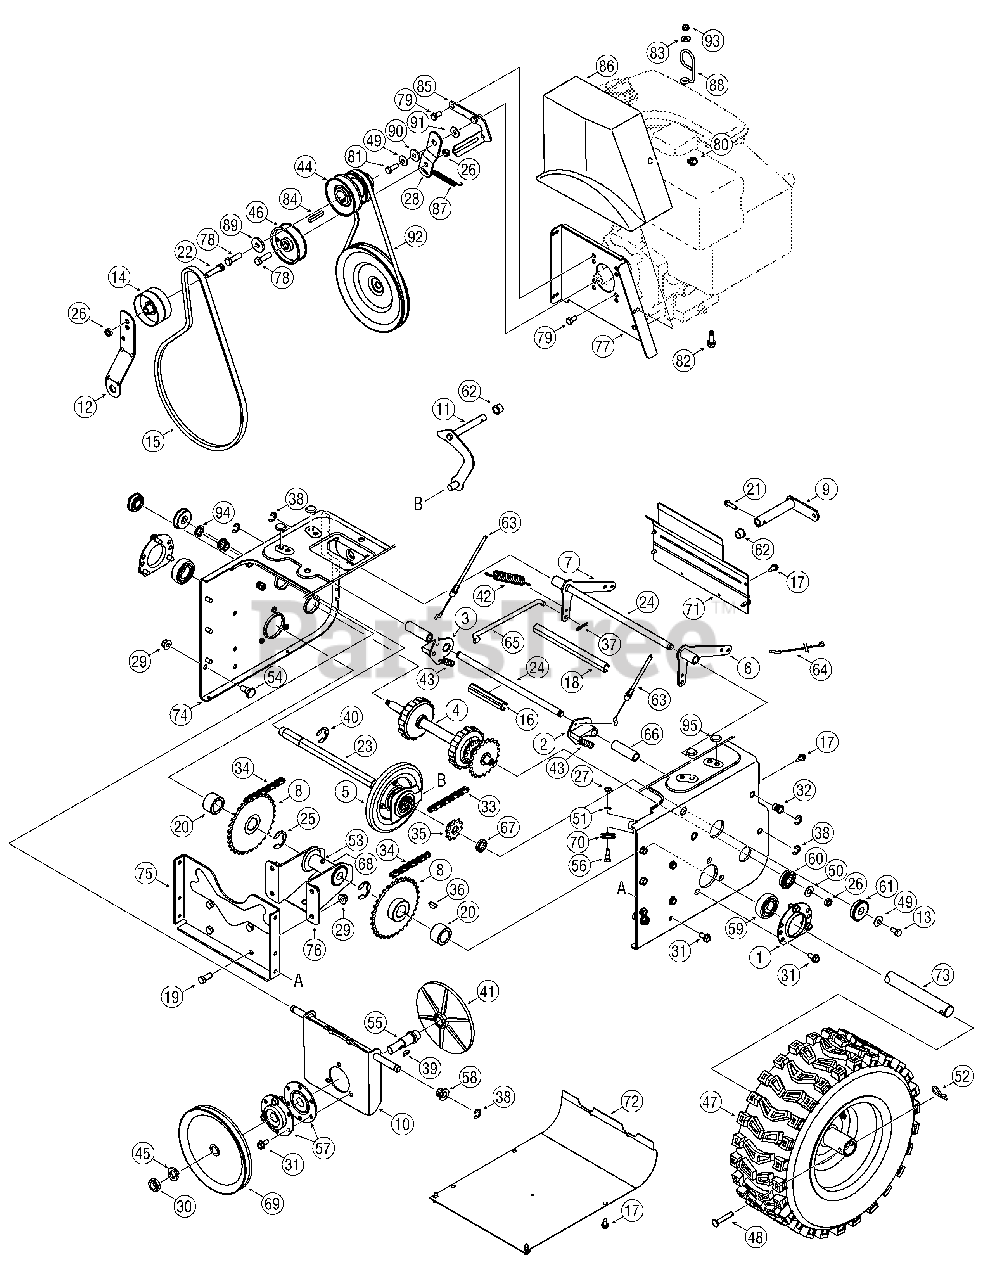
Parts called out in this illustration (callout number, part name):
1	Housing, Bearing
2	Dogg, Steering Drive, LH
3	Dogg, Steering Drive, RH
4	Shaft Assembly, Steering
5	Assembly, Friction Wheel
11	Rod Assembly, Shift
12	Brkt., Idler, Auger
13	Screw, Hex Cap Lock,
14	Idler, Flat, 2.75 OD
15	V-Belt, 1/2 x 44.0
16	Spcr., .51 ID x 3.66 Lg.
17	Screw, Hex Wash.
18	Spcr., .51 ID x 7.895 Lg.
19	Screw, Hex Cap, 3/8-16
20	Spcr., 1.0 ID x 1.50 OD
21	Screw, Hex, 1/4-20 x 1.00
22	Screw, 3/8-24 x 1.50
23	Shaft, Hex Drive
24	Shaft, Actuator
25	Ring, Retainer
26	Nut, Hex Insert Jam Lock
27	Nut, Hex, 1/4-28 GR5
28	Bracket, Idler, Drive
29	Nut, Hx Flnge Insert Lk
30	Nut, Hx Insert Jam Lk
31	TT Screw, 5/16-18 x .750
32	Nut, Insert 3/8-16
33	Chain, Endless, #41 x 36L
34	Chain, #420 x 40L
35	Sprocket, #41 x 10T
36	Key, Woodruff
37	Pin, Internal Cotter
38	E-Ring
39	Key, Hi-Pro, 3/16 x 5/8
40	Ring, Retaining
41	Plate, Drive
42	Spring, Extension
43	Spring, Extension
44	Pulley, Dbl, 3.25 OD
45	Washer, Lock, 5/8
46	Pulley, Flat Idler, 3.0 OD
48	Pin, Clevis
49	Wsh, Bell., .34 x .872 x .06
50	Wash, .406 x .875 x .059
51	Washer, Lock, 1/4
52	Pin, Internal Cotter
53	Fitting, Lube, 3/16 Drive
54	Screw, Shldr., .498 x .34
55	Spindle, Drive Plate
56	Screw, Hex Shldr., 1/4-28
57	Ass’y, Bearing/Housing
58	Bearing, Hex Flange
59	Bearing, Self Aligning
60	Bearing, Ball
61	Bearing, Ball
62	Bush, Flg, .5 ID x .627 OD
63	Cable, Steering
64	Cable, Auger Idler
65	Rod, Drive Clutch
66	Spcr., .514 x .632 x 2.44
67	Spacer, .675 x 1.0 x .23
68	Spcr, .6725 x 1.125 x 2.48
69	Pulley, Drive
70	Roller, Cable
73	Axle, Wheel, 33"
78	Screw, 3/8-14 x 1.25 GR8
79	Screw, 5/16-24 x .625
80	Screw, Hx Wash Hd Tapp
81	Screw, Hx Cap 5/16-24
82	Screw, 3/8-16 x 1.00
83	Wsh, Flat, .28 x .74 x .063
84	Key, Square, 1/4 x 1.5
86	Cover, Belt
87	Spring, Extension
88	Guide, Chute Cable
89	Washer, Flat, .406 x 1.25
90	Spacer, Shoulder
91	Washer, Flat, .349 x .879
92	V-Belt, 3/8 x 35.5
93	Nut, Flg Lk, 1/4-20
94	Nut, Spd.
95	Plug, 3/8 ID
